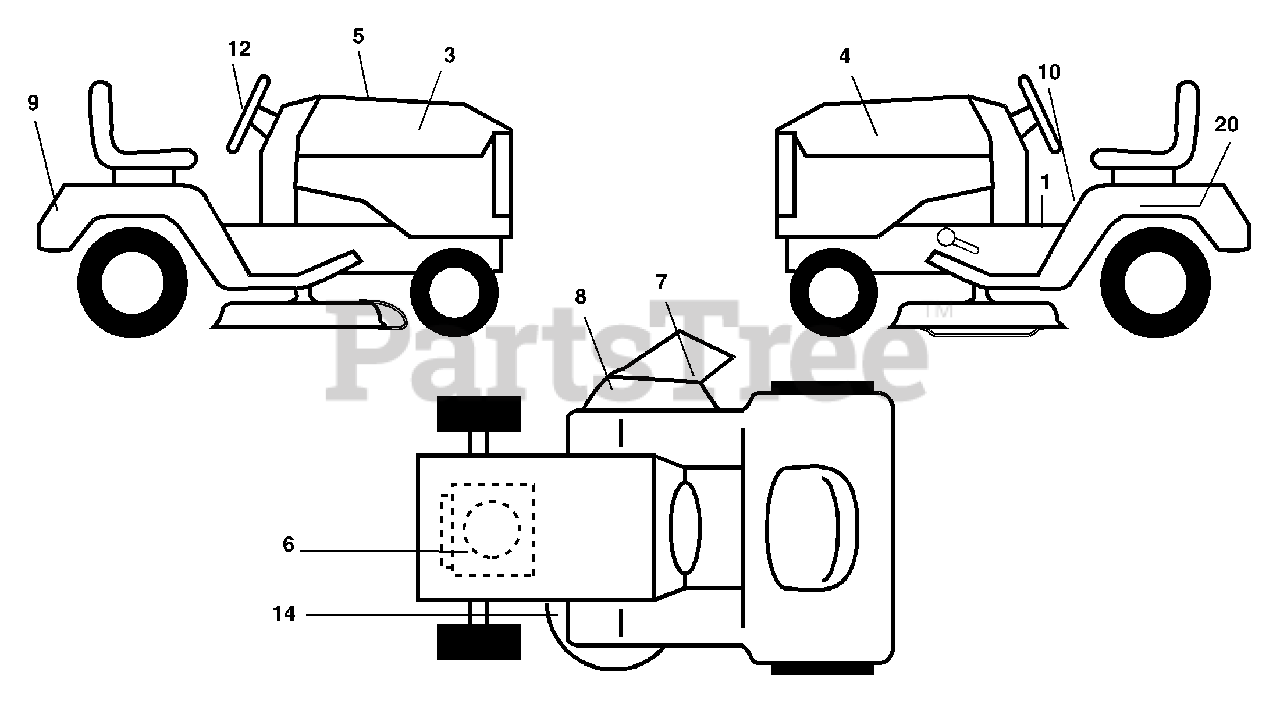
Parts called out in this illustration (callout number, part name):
1	Decal Oper. Step Thru Eng/Fr
3	Decal Hood RH
4	Decal Hood LH
5	Decal Hood Cust.
6	Decal Engine
7	Decal Deck B 42
8	Decal Warning
9	Decal Fender Husq
10	Decal Fender Danger Eng/Fr
12	Decal Steering Wheel
14	Decal V-Belt Schematic
20	Decal Bat Dan/Psn
